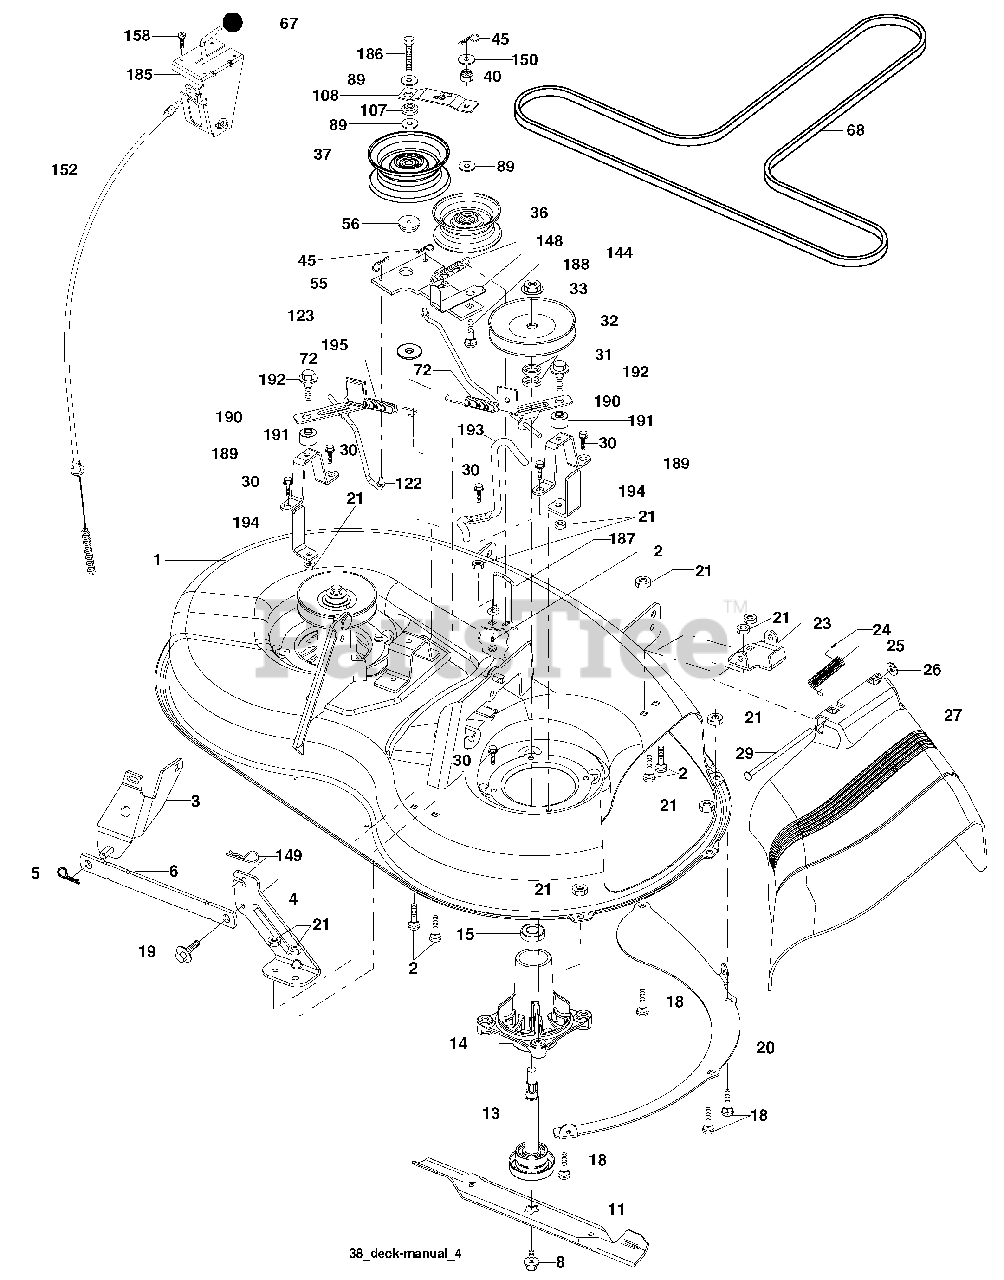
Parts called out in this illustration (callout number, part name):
1	Deck Weldment
2	Bolt Carriage 5/16-18 x 3/4
3	Bracket Asm Fr. Sway Bar
4	Bracket Deck Sway Bar
5	Retainer Spring
6	Bar Sway Deck
8	Bolt/Washer Asm. 7/16-20 unf
11	Blade Mower
13	Shaft Assembly, Mandrel
14	Housing, Mandrel
15	Bearing, Ball, Mandrel
18	Bolt Rdhd Sqnk 5/16-18 x 5/8
19	Bolt, Shoulder
20	Baffl e Vortex Front
21	Nut
23	Bracket, Mower Defl ector
24	Cap, Sleeve
25	Spring, Torsion, Defl ector
26	Nut, Push
27	Shield, Defl ector
29	Rod, Hinge
30	Screw Thdrol.
31	Washer, Spacer
32	Pulley, Mandrel
33	Nut, Toplock
36	Pulley, Idler, Flat
37	Pulley Idler Flat 3.75
40	Nut, Crownlock 3/8-16 unc
45	Retainer
55	Idler Arm Assembly
56	Spacer, Retainer
67	Knob
68	V-Belt
72	Spring Brake Return
89	Washer 13/32 x 13/16 x 11 Ga.
107	Spacer Retainer
108	Stiffener, Idler Arm
122	Linkage, Brake LH
123	Linkage, Brake RH
144	Keeper Belt Idler Tension
148	Spring Return Idler
149	Retainer Spring Yellow
150	Washer 9/32 x 3/4 x 10 Ga.
152	Clutch Cable 38"
158	Screw Hex Thd Cut 1/4-20 x 1/2
185	Head Asm Cable Clutch
186	Screw Hex Wsh Thdrol 3/8-16 x 2-3/4
187	Keeper Belt
188	Bolt Carriage Idler
189	Stand, Brake
190	Arm, Brake
191	Spacer, Brake
192	Bolt/Washer Asm 5/16-18
193	Keeper Belt Rh Mandrel
194	Guard, Brake
195	Washer 13/32 x 2 x 10 Ga.
195	Brake Assembly
195	Mandrel Assembly
195	Replacement Mower, Complete
